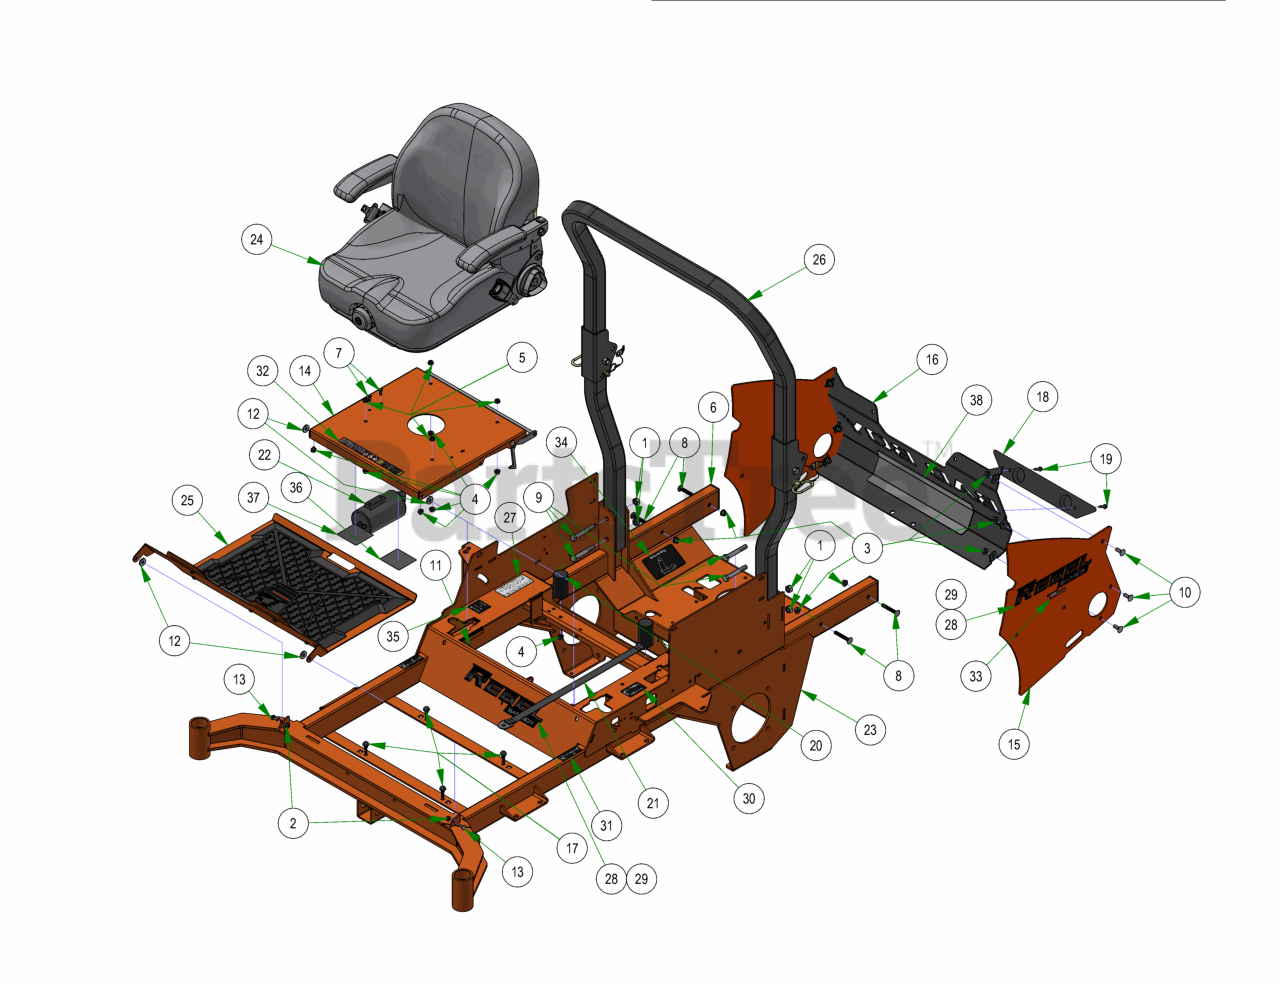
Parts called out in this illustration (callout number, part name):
1	1/2-13 HEX 2-WAY REVERSIBLE CENTER LOCKNUT Grade B ZINC
2	1/4-20 NYL INSERT FLANGE LOCKNUT ZINC
3	3/8-16 NYLON INSERT FLANGE LOCKNUT (GR.F) ZINC
4	5/16-18 NYLON INSERT FLANGE LOCKNUT ZINC
5	5/16-18 HEX SERRATED FLANGE NUT HARD/ZINC
6	1 1/2 x 3 Frame Plug
7	M6-1.0 X 16MM DIN 933 HEX TAP BOLT (CL 8.8) ZINC
8	3/8" x 2 1/2" Carriage Bolt
9	1/2-13 X 3-1/4 HEX CAP SCREW (GR.5) ZINC
10	3/8-16 X 1 CARRIAGE BOLT (GR.5) ZINC
11	5/16-18 X 1 CARRIAGE BOLT (GR.8) ZINC
12	.360 ID X .983 OD X .120 THICK FLAT WASHER NYLON
13	1/4-20 X 3/4 CARRIAGE BOLT (GR.5) ZINC
14	R-SERIES SEAT PLATE ASSEMBLY
15	Rebel Rear Cover Side Plate
16	2019 Vertical Rear Cover Tailgate - Black
17	2023 Floor Board Rubber Bumper
18	2017 XP BUMPER
19	1/4-14 X 1-1/4 HEX WASHER UNSLOT TEK/3 ZINC
20	2019 Bad Boy X Cylindrical Seat Mount
21	Seat Strap with Buckles
22	2019 Outlaw EPA Cannister Assembly
23	2023 Rebel Frame - Painted
24	2022 Suspension Seat w/Seatbelt
25	2024 R-Series Floorboard Assembly
26	2019 2X2 Folding ROPS
27	2024 EPA Build Date Punch Decal
28	Rebel back Plate & Front Decal
29	Rebel X back Plate & Front Decal
30	2018 Out/XP/Diesel Brake Decal
31	2018 LH/RH Steering Control Decal Roll
32	Outlaw Warning Decal
33	2022 Powered By Kawasaki Decal
34	2019 Rebel Pump Belt Route Decal
35	2019 Deck Release Decal
36	Control Adj. Control Rod Decal
37	Control Adj. Control Dampener Decal
38	Heat Shield (Fiberglass Adhesive)
